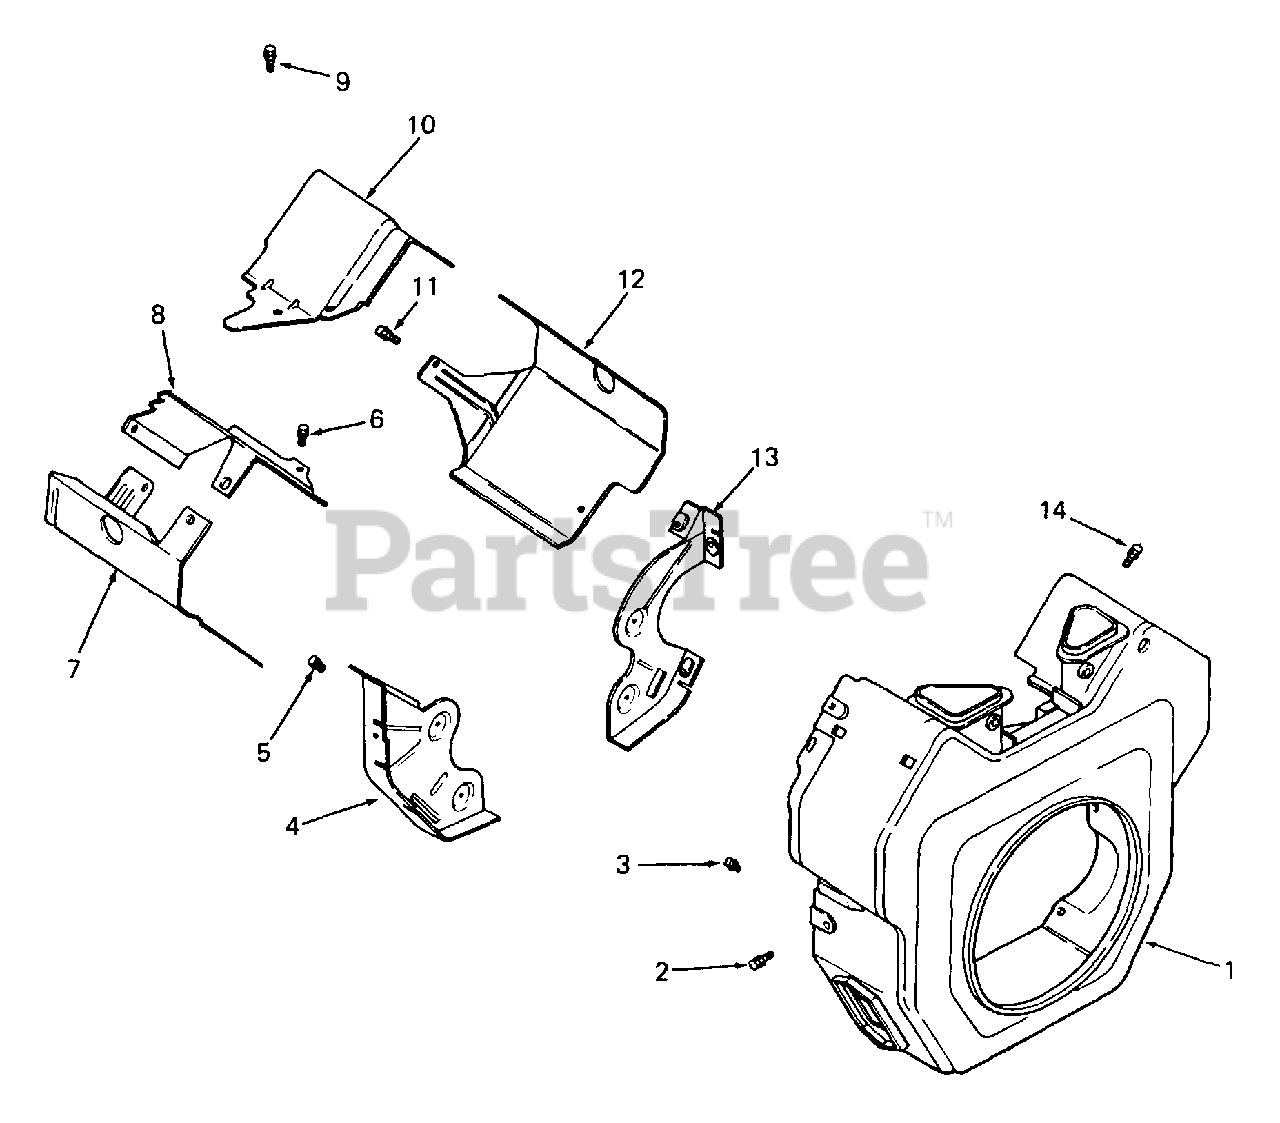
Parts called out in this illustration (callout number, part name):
1	Housing, Blower
2	Screw, M5 x 0.8 x 16
3	Screw, M5 x 0.8 x 14
4	Plate, Backing #2 Side
5	Screw, M6 x 1.0 x 16
6	Screw, M6 x 1.0 x 16
7	Baffle, Cylinder Barrel #2 Side
8	Baffle, Valley #2 Side
9	Screw, M5 x 0.8 x 10
10	Baffle, Valley #1 Side
11	Screw, M5 x 0.8 x 16
12	Baffle, Cylinder Barrel #1 Side
13	Plate, Backing #1 Side
14	Screw, M5 x 0.8 x 20
